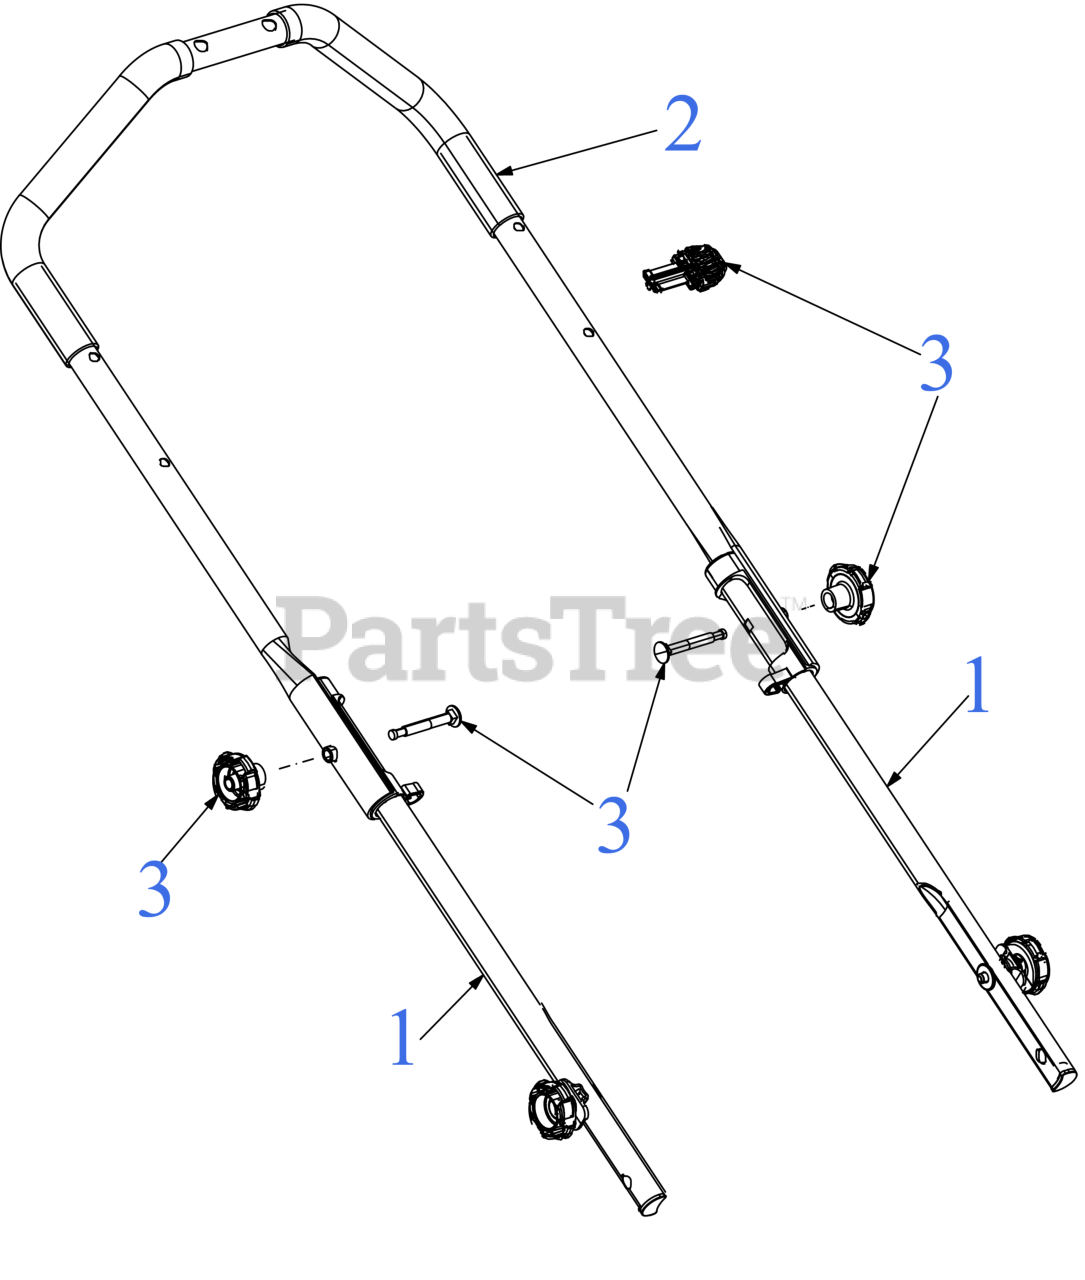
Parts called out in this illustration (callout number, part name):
1	LOWER HANDLE (DeWALT)
2	HANDLE (UPPER)
3	HARDWARE KIT (KNOB/KEY) (BLACK)
